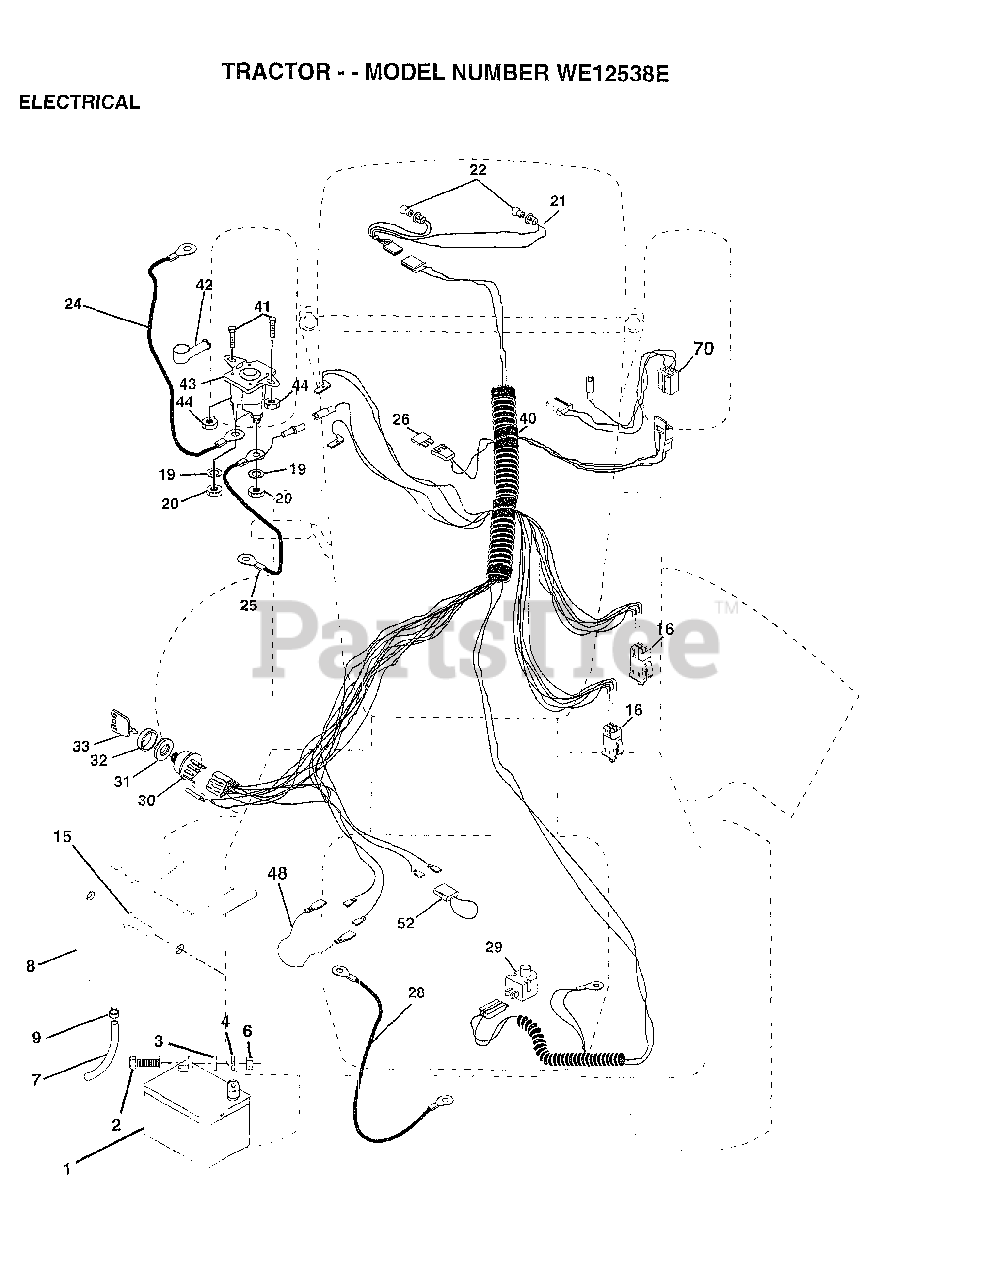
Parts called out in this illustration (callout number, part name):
2	BOLT LT
3	WASHER
4	LOCKWASHER
7	TUBE T
8	"CASE,BATTERY.MECH"
9	HOSE CLAMP T
15	FASTNER.SNAP-IN
16	SWITCH INTERLOCK
20	NUT
21	"HARNESS,LIGHT SOC"
22	HEADLAMP BULB
24	"CABLE T, BATTERY"
25	CABLE.BTRY.6GA.RD
26	FUSE HYT
28	CABLE T
29	SWITCH SEAT
30	SWITCH IGN 4POS
31	NUT IGNITION
32	COVER KEY SWITCH
33	KEY
40	HARNESS-IGNITION
41	BOLT HXHD FIN
44	NUT HXKEP 1/4X20
48	ADAPTER AMMETER
52	PROTECTION LOOP
70	HARNESS ENG DUAL
